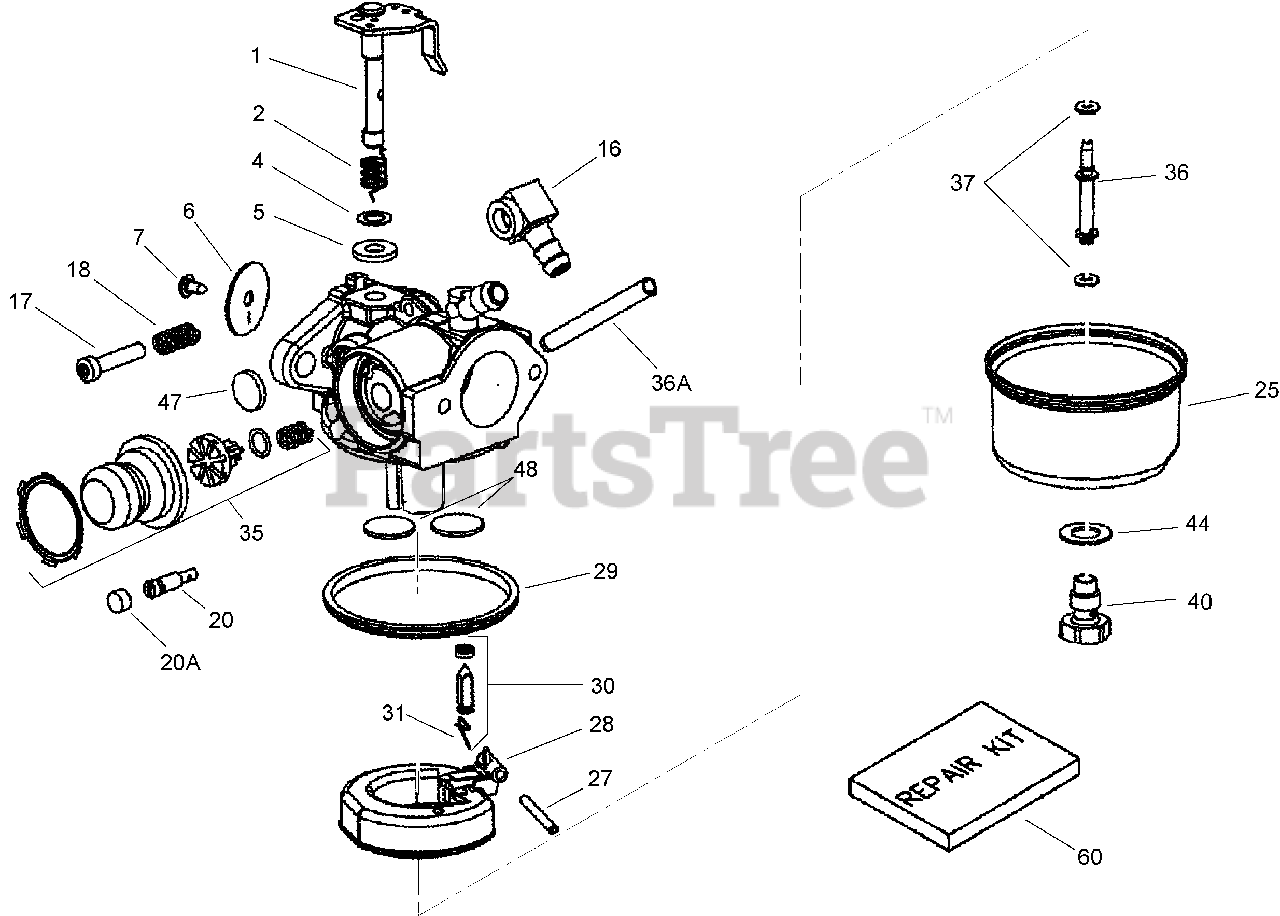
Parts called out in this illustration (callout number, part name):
1	Throttle Shaft and Lever ASM
2	Spring-Return, Throttle
4	Washer-Seal, Dust
5	Dust Seal (Throttle)
6	Shutter-Throttle
7	Screw-Shutter
16	Fitting-Fuel
17	Screw-Throttle Crack/Idle Speed
18	Spring-Tension
20	Screw-Restrictor, Idle
20A	Cap-Screw, Restrictor Idle
25	Bowl-Float (no drain)
27	Shaft-Float
28	Float (Plastic)
29	O-Ring-Bowl, Float
30	Inlet Needle, Seat and Clip ASM (Includes 31)
31	Clip-Spring
35	Primer Bulb/Valve Repair Kit
36	Tube-Nozzle, Main
36A	Tube-Carburetor
37	O-Ring-Nozzle Tube, Main
40	Nut-Bowl, High Speed
44	Washer-Nut, Bowl
47	Plug-Welch, Idle Mixture Well
48	Plug-Welch, Atmospheric Vent
60	Repair Kit
